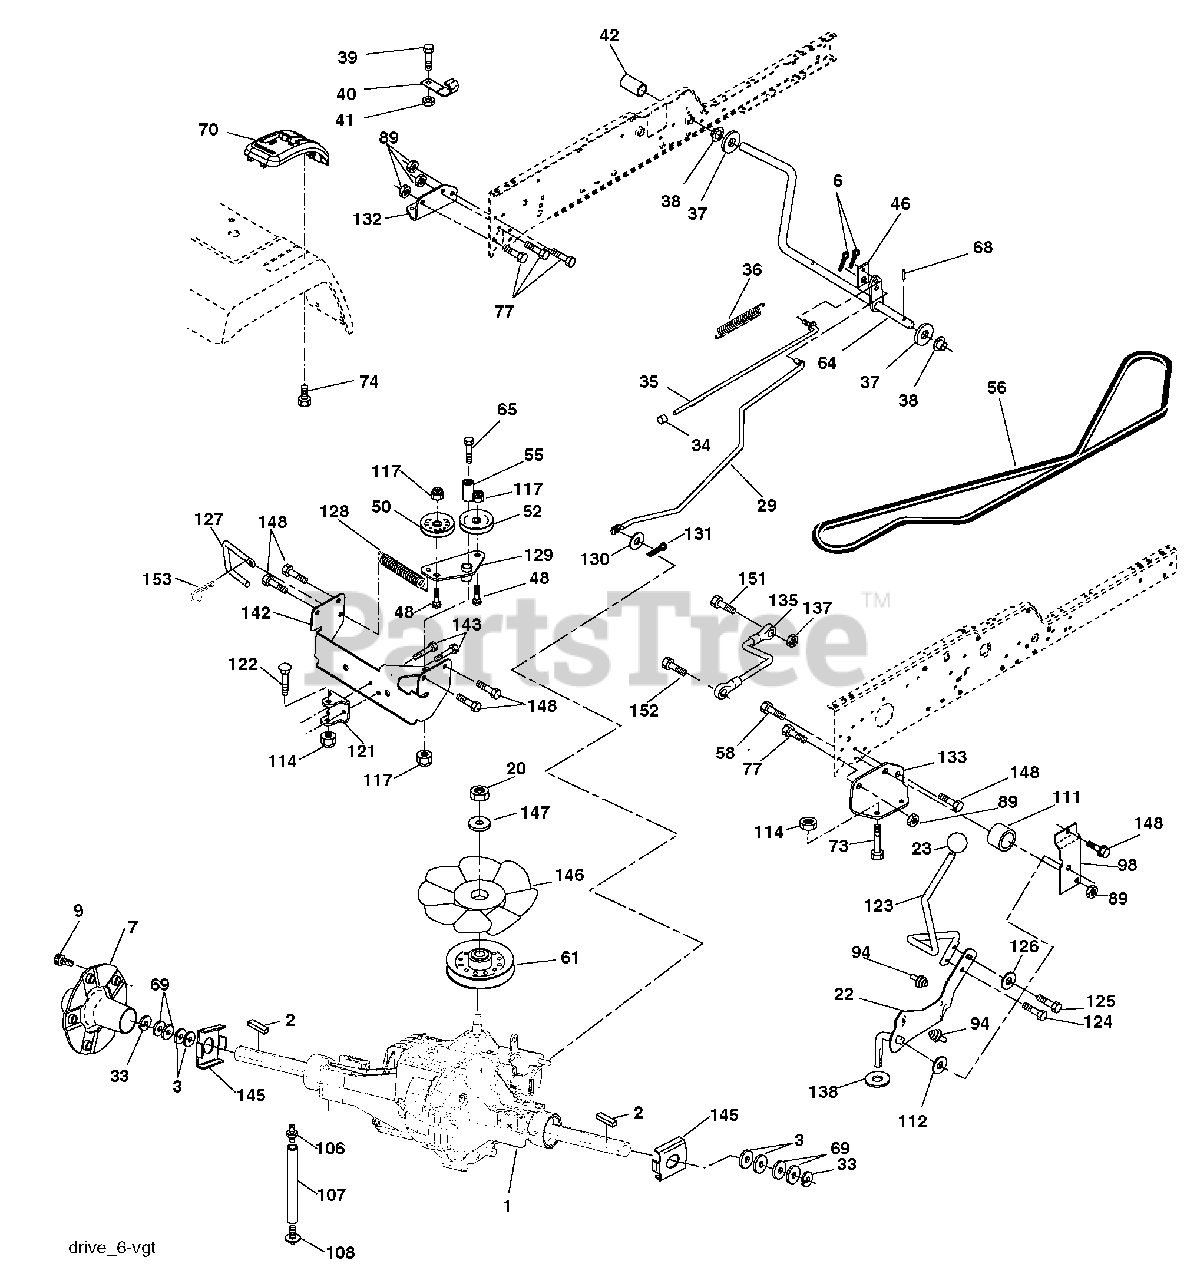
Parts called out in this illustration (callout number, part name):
2	Key Sq. 1/4 x 2.5
3	Washer Thrust
6	Pin, Cotter
7	Wheel, Hub Assembly
9	Bolt, Hub
20	Nut
22	Lever Asm Shift
23	Knob
29	Brake, Rod
33	Ring E
34	Cap, Parking Brake
35	Rod, Parking Brake
36	Spring, Drive Ground
37	Washer 25/32 x 1-1/4 x 16 Ga.
38	Nyliner
39	Screw, Fin. #10-24 x 1
40	Actuator, Interlock Switch
41	Nut Centerlock 10-24 unc
42	Cover, Pedal
46	Retainer, Spring
48	Bolt Carr. Shoulder 3/8-16 x 1-3/4 Gr. 5
50	Pulley, Idler, Flat
52	Pulley, Idler, Grooved
55	Bearing, Idler
56	V-Belt
58	Bolt Fin Hex 7/16-14 x 1-1/2
61	Pulley, Transaxle
64	Shaft, Brake Pedal
65	Bolt, Shoulder
68	Pin, Roll
69	Washer
70	Console Shift
73	Bolt Hex Flghd 5/16-18 x 3 Gr. 5
74	Screw Hex Wsh. Hi-Lo 1/4-1/2
77	Bolt Fin Hex 7/16-14 x 1
89	Nut Crownlock 7/16-14 Unc
94	Fastener Christmas Tree
98	Bracket Shift
106	O-Ring Asm Hydro Gear
107	Line Fuel Hydro 15” VGT
108	Cap Asm Vent Hydro Gear
111	Spacer Shift Lever VGTH
112	Washer Nylon High Temp
114	Nut Lock Hex W/Ins 5/16-18 Unc
117	Nut, Lock Flg. 3/8-16
121	Bracket Strap Torque
122	Bolt 5/16-18 x 2.50
123	Rod Shift
124	Bolt Shoulder 5/16-18 x .561
125	Screw 5/16-18 x 5/8
126	Washer SRRTD 5/16 ID x 1.0 x.125
127	Link Control Clutch
128	Spring Drive GRND
129	Bracket Asm Idler Tensioning
130	Washer 13/32 x 5/8 x 16 Ga.
131	Pin Cotter 3/32 x 3/4
132	Bracket Mtg Hydro 3500 LH VGT
133	Bracket Mtg Hydro 3500 RH VGT
135	Link Asm Control Hydro 3500
137	Nut Lock 5/16-18 NC Thd.
138	Washer Thrust 5/8 x 1.10 x 1/32
142	Strap Torque HG-3500
143	Screw 5/16-18 x 3/4
145	Washer Axle Flange HG-3000
146	Fan 7" Hydro
147	Washer
148	Bolt Hex 7/16-14 x 1-1/4 Gr. 5
151	Bolt Fin Hex 5/16-18 x 7/8
152	Bolt Hex 5/16-18 x 1
153	Spring Retainer
